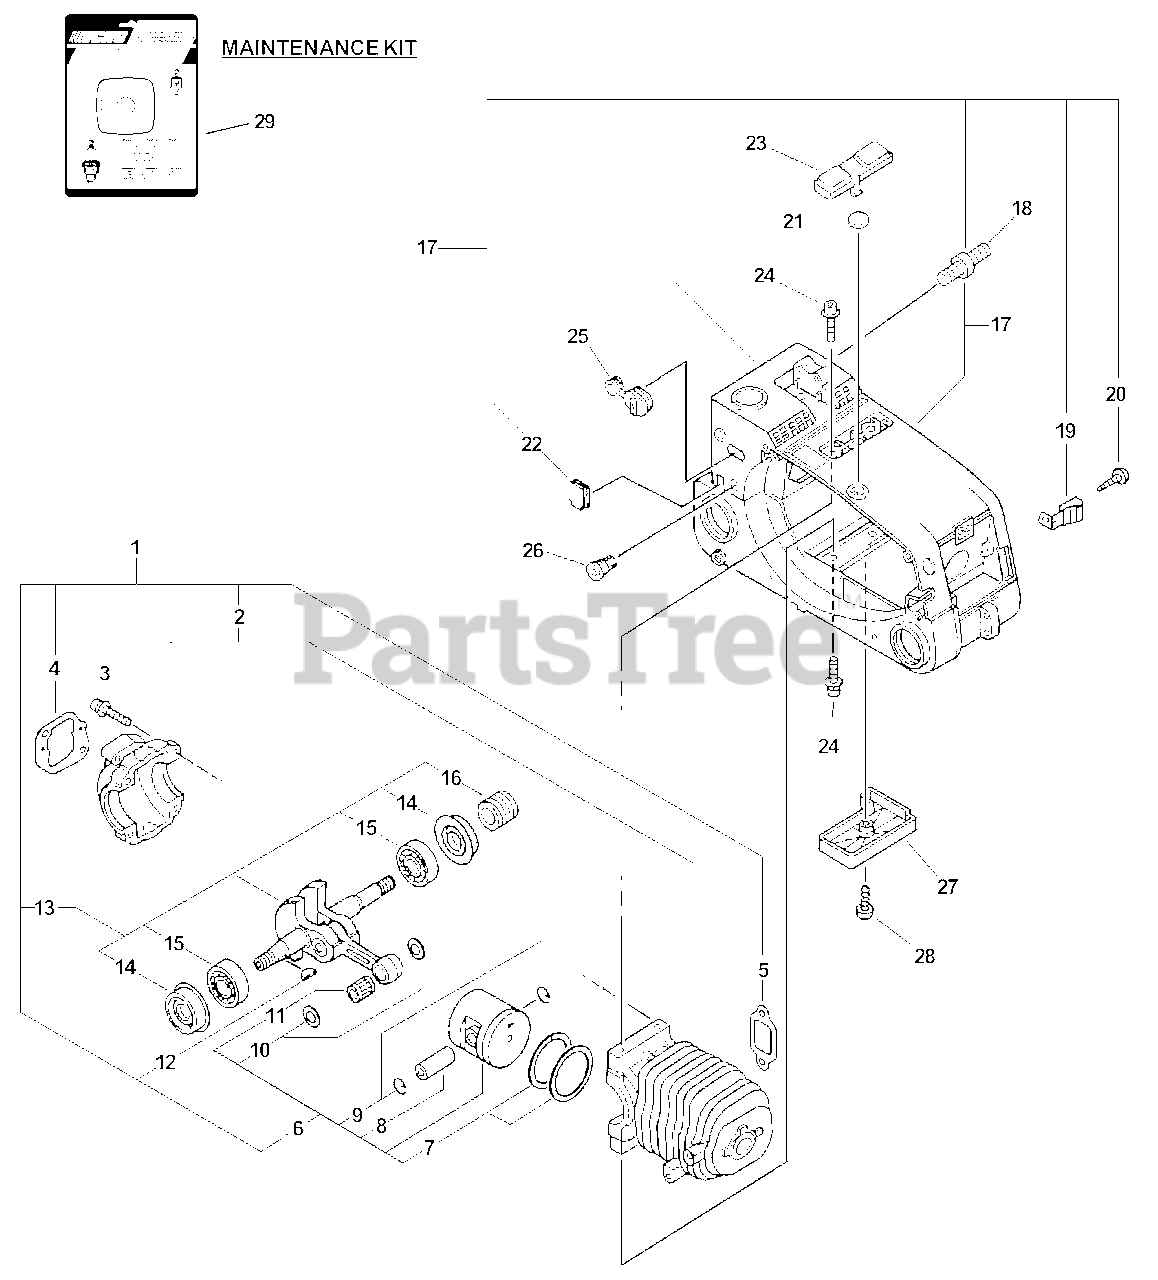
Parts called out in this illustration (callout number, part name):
1	SHORT BLOCK -- SB1019
2	CRANKCASE SET
3	SCREW - 5X25
4	GASKET, INTAKE
5	GASKET, EXHAUST
6	PISTON KIT
7	RING, PISTON
8	PIN, PISTON
9	RING, RETAINING
10	SPACER, PISTON
11	BEARING, NEEDLE
12	KEY
13	CRANKSHAFT ASSY
14	SEAL, OIL
15	BEARING, BALL - 6201
16	GEAR - WORM
17	ENGINE COVER KIT
17	COVER, ENGINE - GRAY
18	STUD, GUIDE BAR
19	LATCH
20	SCREW - 4X10
21	PLUG
22	PLUG
23	COVER - GRAY
24	SCREW - 5X16
27	COVER, BOTTOM - GRAY
28	SCREW - 4X16
29	RePower MAINTENANCE KIT
30	FILTER, AIR
31	FILTER, FUEL
32	SPARK PLUG -- BPM-7A
